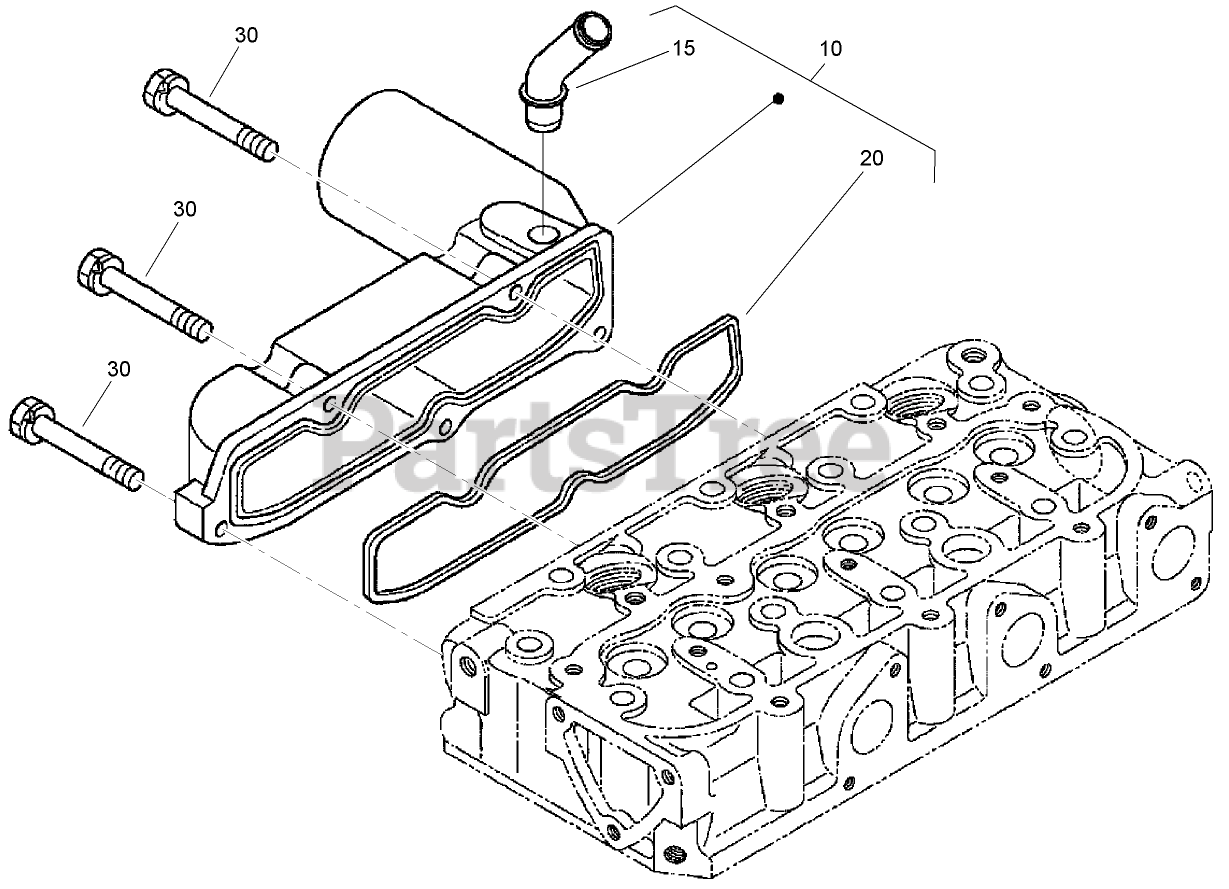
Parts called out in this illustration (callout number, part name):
10	INLET MANIFOLD ASM
15	PIPE-BREATHER
20	GASKET-MANIFOLD, INTAKE
